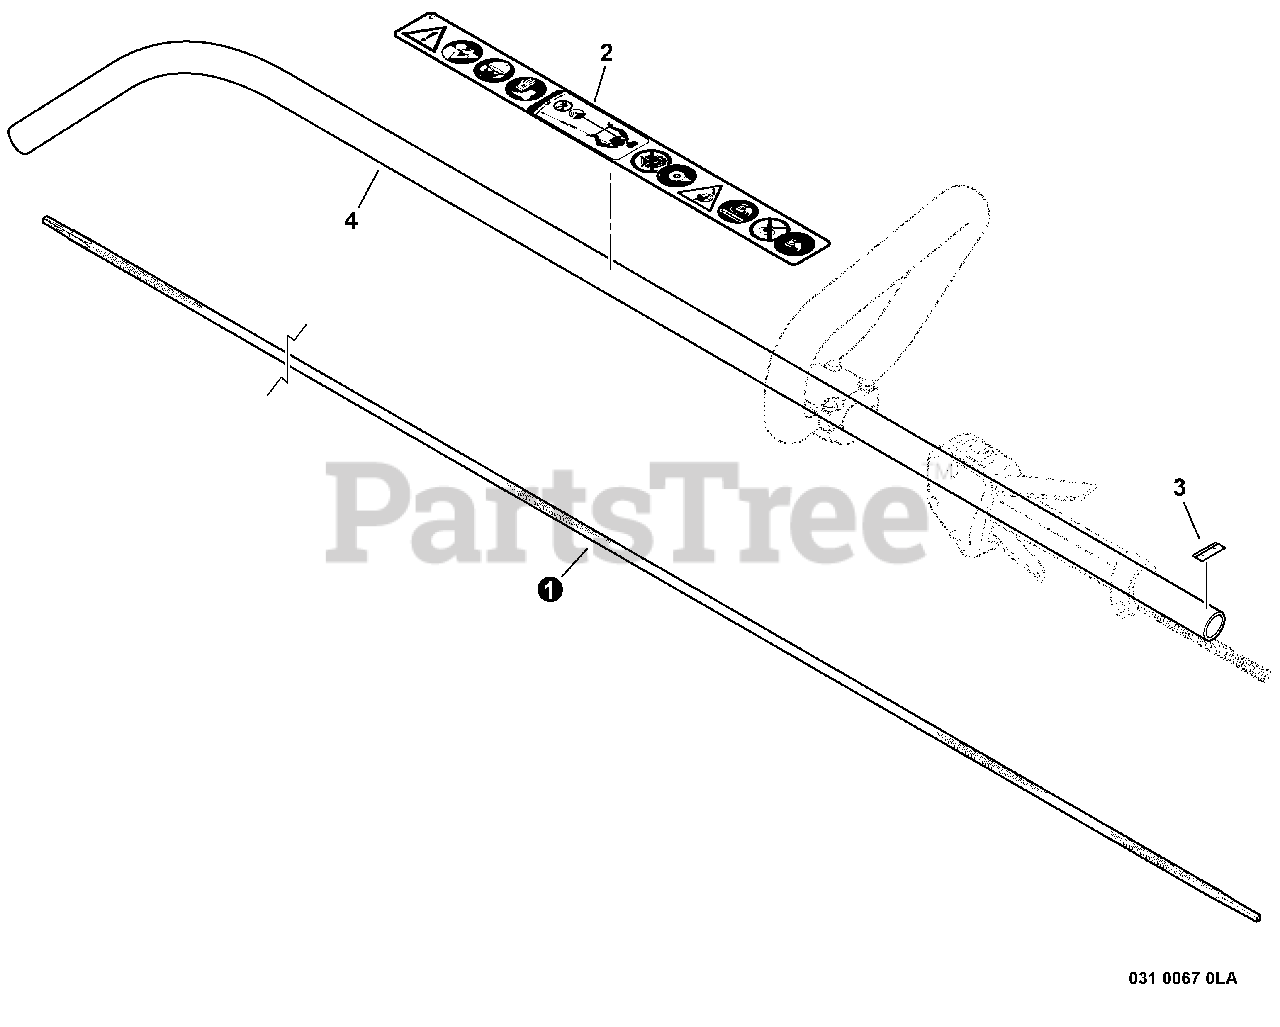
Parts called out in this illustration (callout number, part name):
1	DRIVESHAFT - FLEXIBLE
2	LABEL, ISO CAUTION
3	LABEL - ALIGNMENT
4	PIPE, MAIN
